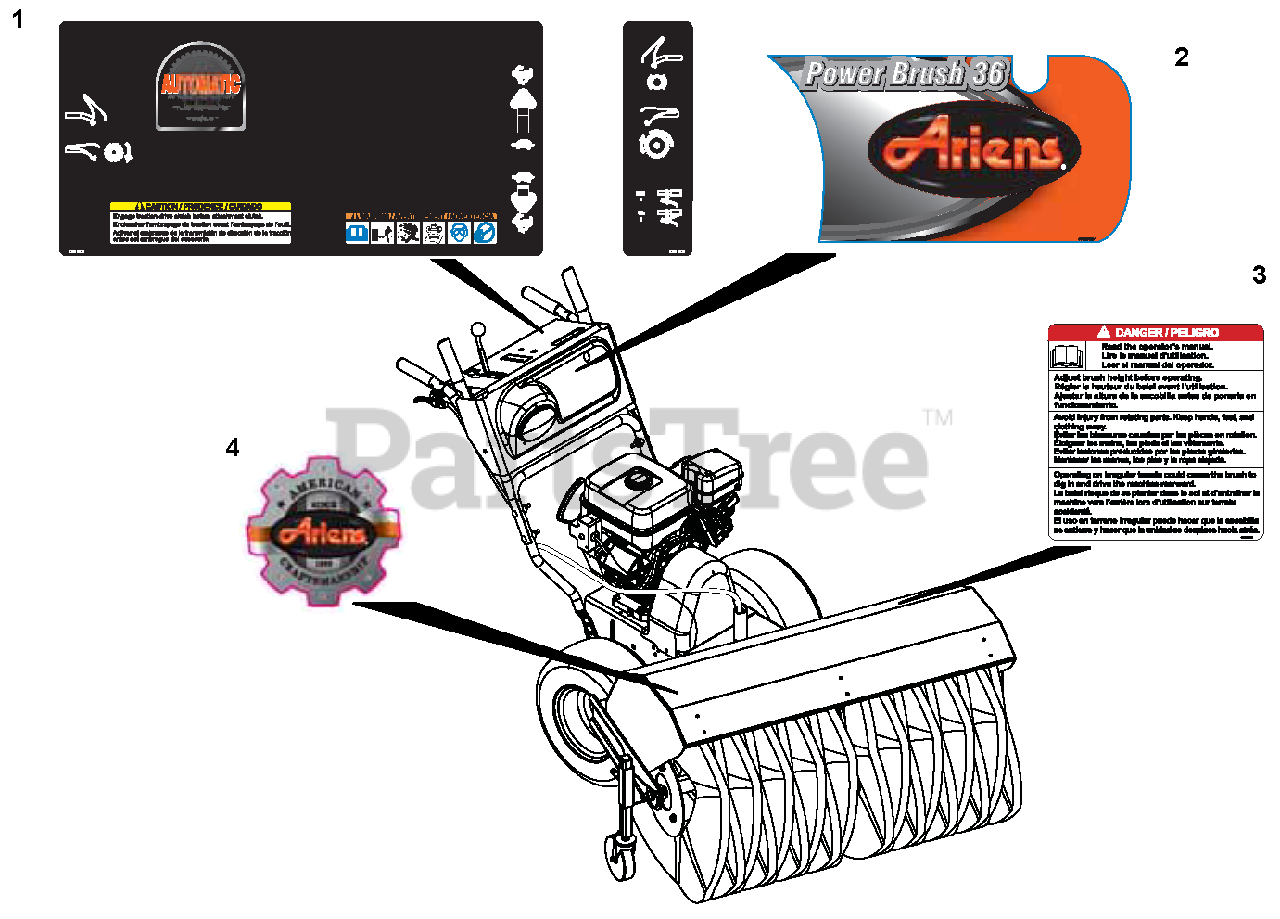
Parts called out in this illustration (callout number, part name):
1	DECAL, CONTROL-BRUSH
2	DECAL, FRONT-ARIENS PB36
3	DECAL, DANGER - POWER BRUSH
4	Decal, Ariens Heritage - Large
